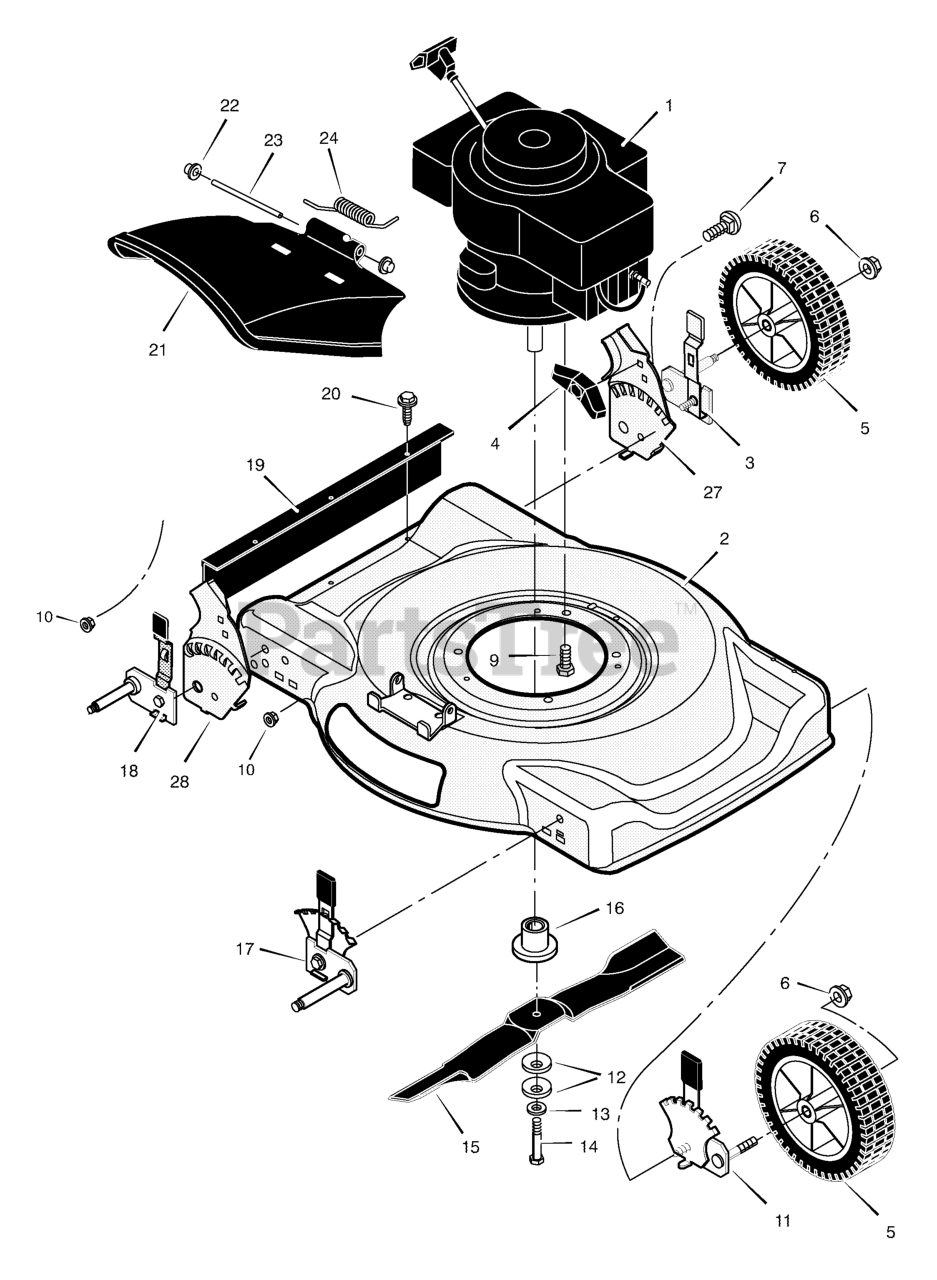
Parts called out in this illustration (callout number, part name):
1	Engine
2	Housing
3	Height Adjuster, Left Rear
5	Wheel and Tire
6	Locknut, Flange
7	Bolt, Carriage
9	Bolt, Engine
10	Nut
11	Height Adjuster, Left Front
12	Washer, Belleville
14	Bolt, Hex
15	Blade, Side Discharge
16	Adapter, Blade
17	Height Adjuster, Right Front
18	Height Adjuster, Right Rear
19	Guard, Rear
21	Deflector, Chute
22	Push--On Cap
23	Pin, Pivot
27	Bracket, Left Handle
28	Bracket, Right Handle
